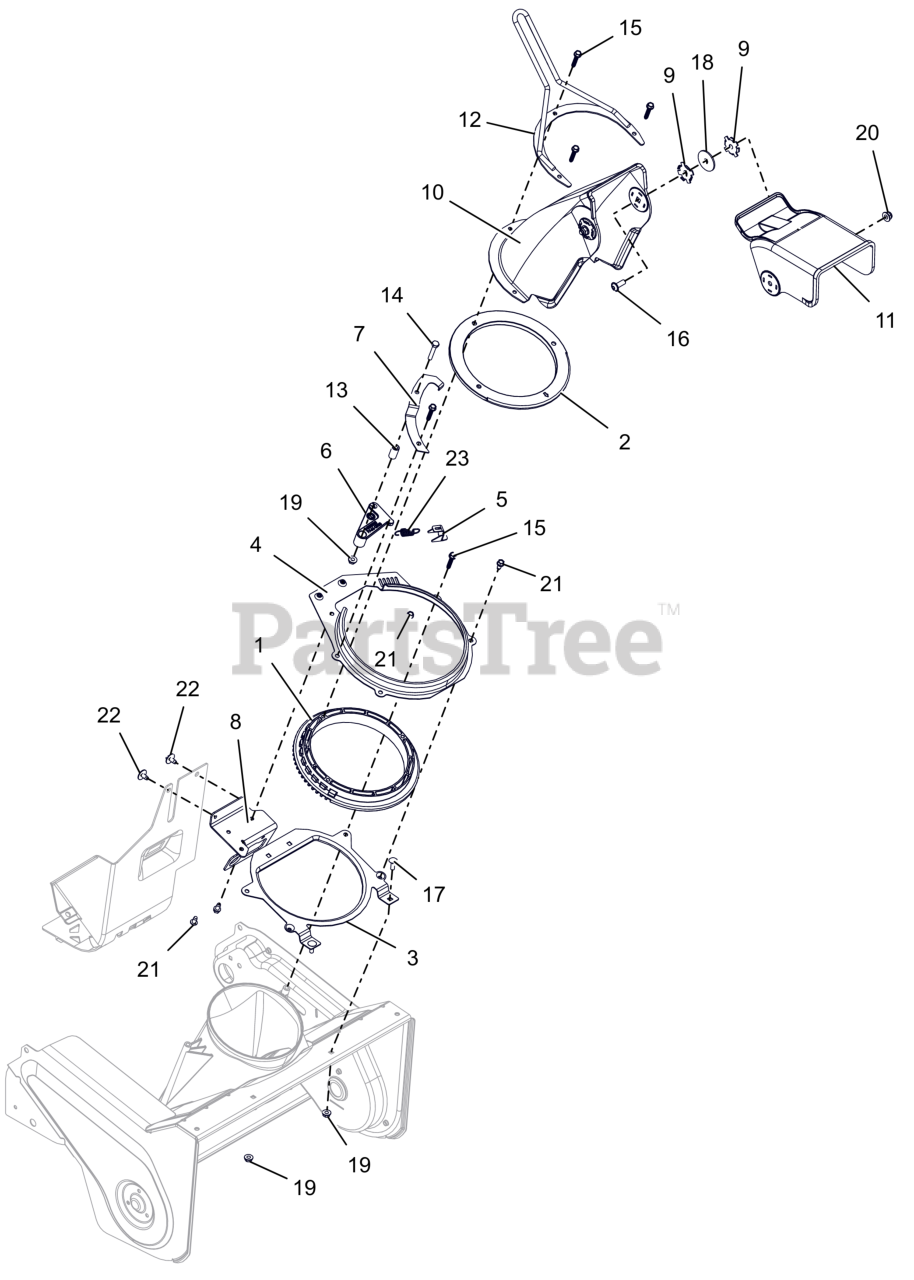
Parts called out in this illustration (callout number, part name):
1	GEAR, CHUTE RING
2	GUARD, WATER
3	RING, CHUTE MOUNT - LOWER
4	RING, CHUTE MOUNT - UPPER
5	BRKT, SPRG
6	ARM, PAWL
7	PAWL ARM STOP
8	BRKT, CHUTE ROTATION - REAR
9	PLATE, FRICTION
10	CHUTE, DISCHARGE-SINGLE STAGE
11	CAP, CHUTE-SINGLE STAGE
12	HANDLE, ROTATION - MANUAL
13	BSHG, SLV .265X.505X.995
14	BLT, HEX .25-20X1.50 G5 ZCC
15	SCR,PLASTITE .25-10X1.25 ZCC
16	SCR,BTN-FLG .31-18X0.875
17	BLT, RHSN .25-20X.750 G5 ZCC
18	WSHR,FRICTION-.332X1.525X.094
19	NUT-LK-TOP-FLG .250-20 GF ZCC
20	NUT,LK-NYL-FLG .31-18 G5ZC120
21	SCR-TAP .25-20X.50 HWH ZCC
22	SCR, TAP .25-20X.50 LG HWH ZCC
23	SPRG, TENSION .052X.520X1.74
